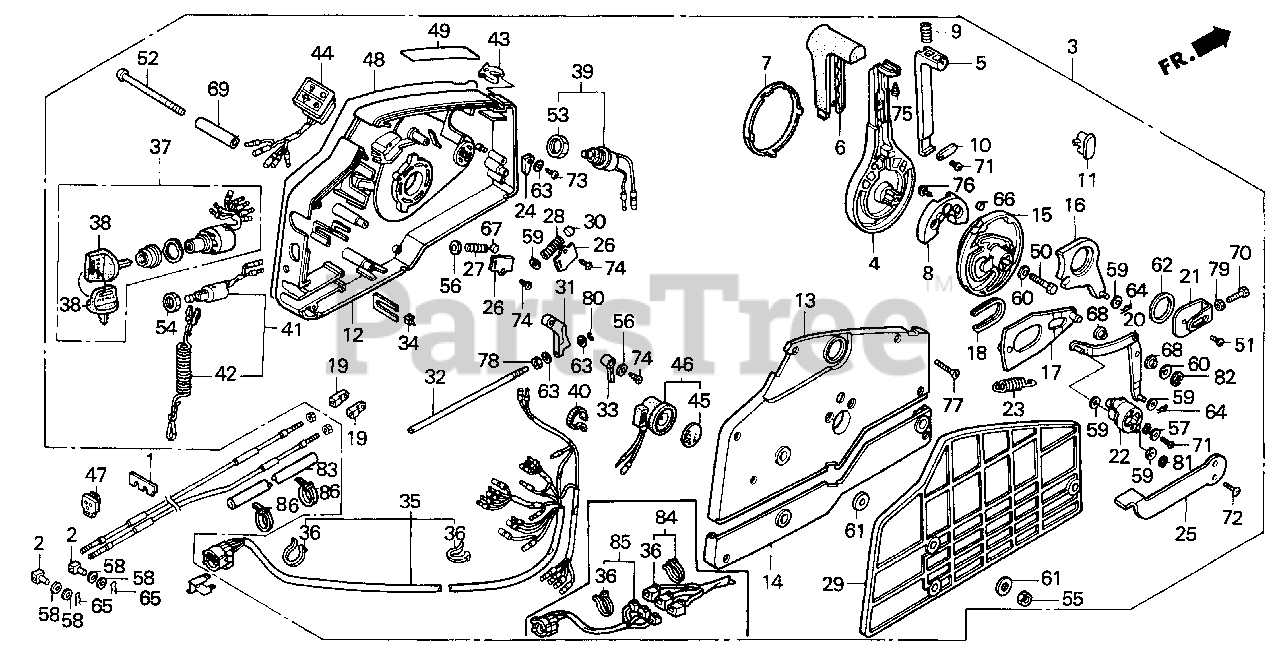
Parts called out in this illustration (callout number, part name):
1	PLATE, REMOTE CONTROL CABLE
2	PIVOT, SHIFT
3	BOX ASSY., REMOTE CONTROL
4	HANDLE, REMOTE CONTROL
5	LEVER, HANDLE LOCK
6	GRIP, REMOTE CONTROL HANDLE
7	CAP, HANDLE
8	BLOCK, NEUTRAL LOCK
9	SPRING, REMOTE CONTROL HANDLE
10	PLATE, LEVER SETTING
11	COVER, GRIP
12	HOUSING, REMOTE CONTROL BOX (A)
13	HOUSING, REMOTE CONTROL BOX (B)
14	HOUSING, REMOTE CONTROL BOX (C)
15	WHEEL, CONTROL
16	ARM, SHIFT LINK
17	PLATE, SLIDING
18	COLLAR, SLIDING PLATE
19	PIVOT, SHIFT
20	ARM, LINK JOINT
21	BRACKET, LINK JOINT
22	WHEEL, ACCELERATOR
23	SPRING, ACCELERATOR WHEEL
24	CAM, STARTER SWITCH
25	LEVER, IDLE
26	PLATE, SPRING SETTING
27	SPRING, SHIFT CLICK
28	SPRING, CHOKE RETURN
29	SPACER, REMOTE CONTROL BOX
30	SPACER, CLICK SPRING
31	BLOCK, THROTTLE FRICTION
32	BOLT, FRICTION
33	SPACER, NEUTRAL SWITCH
34	SPACER, CABLE CLAMP
35	CABLE ASSY., REMOTE CONTROL (B)
36	TIE, CABLE
37	SWITCH ASSY., COMBINATION
38	KEY ASSY., COMBINATION SWITCH
39	SWITCH ASSY., SOLENOID
41	SWITCH ASSY., EMERGENCY STOP
42	WIRE, EMERGENCY
43	CLIP, EMERGENCY LOCK
44	LAMP ASSY., INDICATOR
45	PLATE, TURN SIGNAL BUZZER
46	BUZZER, WARNING
47	GROMMET, CASE (LOWER) (A)
48	PLATE, REMOTE CONTROL
49	MARK, FAST IDLE
50	BOLT, HEX. (8X35)
51	SCREW, PAN (6X10)
52	SCREW (6X95)
53	NUT, HEX. (20MM)
54	NUT, HEX. (16MM)
55	NUT, HEX. (6MM)
56	WASHER, PLAIN (5MM)
57	WASHER, PLAIN (5MM)
58	WASHER, PLAIN (6MM)
59	WASHER, PLAIN (6MM)
60	WASHER, PLAIN (8MM)
61	WASHER (6MM)
62	WASHER (28MM)
63	WASHER, PLAIN (4MM)
64	PIN, LOCK (6MM)
65	PIN, SPECIAL LOCK (6MM)
67	ROLLER, CLICK
68	COLLAR, LINK JOINT
69	COLLAR, DISTANCE (6X10X43.5)
70	BOLT, HEX. (5X16)
71	SCREW, PAN (5X10)
72	SCREW, OVAL (5X12)
73	SCREW, TAPPING (4X10)
74	SCREW, TAPPING (5X10)
75	SCREW, TAPPING (5X12)
76	SCREW, TAPPING (6X16)
77	SCREW, TAPPING (5X25)
78	NUT, HEX. (6MM)
79	NUT, HEX. (5MM)
80	E-RING (3MM)
81	E-RING (4MM)
82	E-RING (7MM)
83	TUBE, CORRUGATED (28MM)
84	CABLE ASSY., REMOTE CONTROL (B)
85	CABLE (14WIRE) (16.5')
86	BAND, SELF-LOCK
